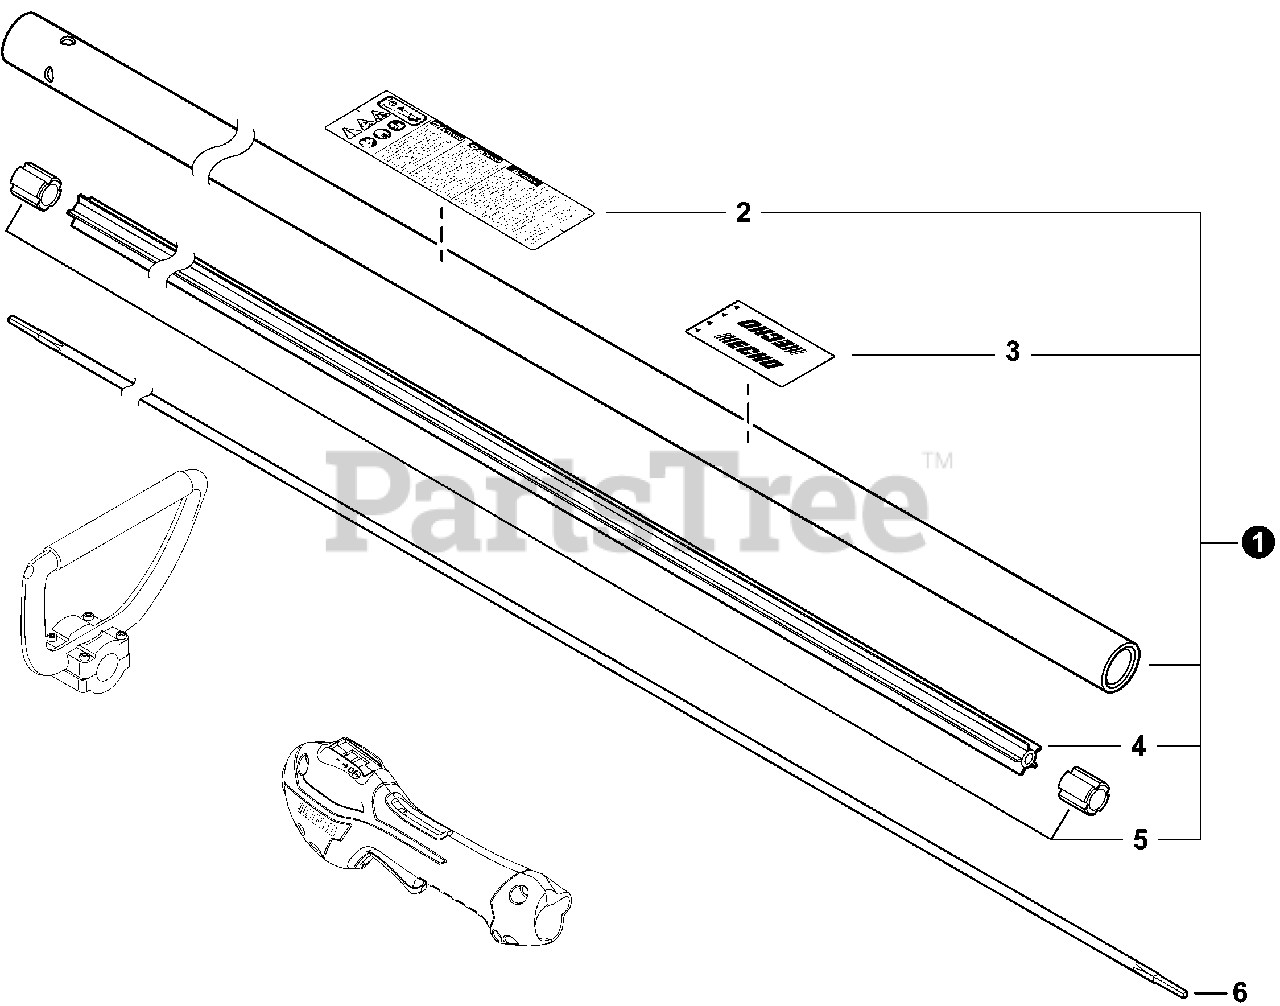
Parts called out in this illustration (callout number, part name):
1	MAIN PIPE ASSY
2	LABEL, CAUTION
3	LABEL, HANDLE LOCATION
4	LINER, FLEXIBLE 21.6×1420
6	DRIVESHAFT - FLEXIBLE
